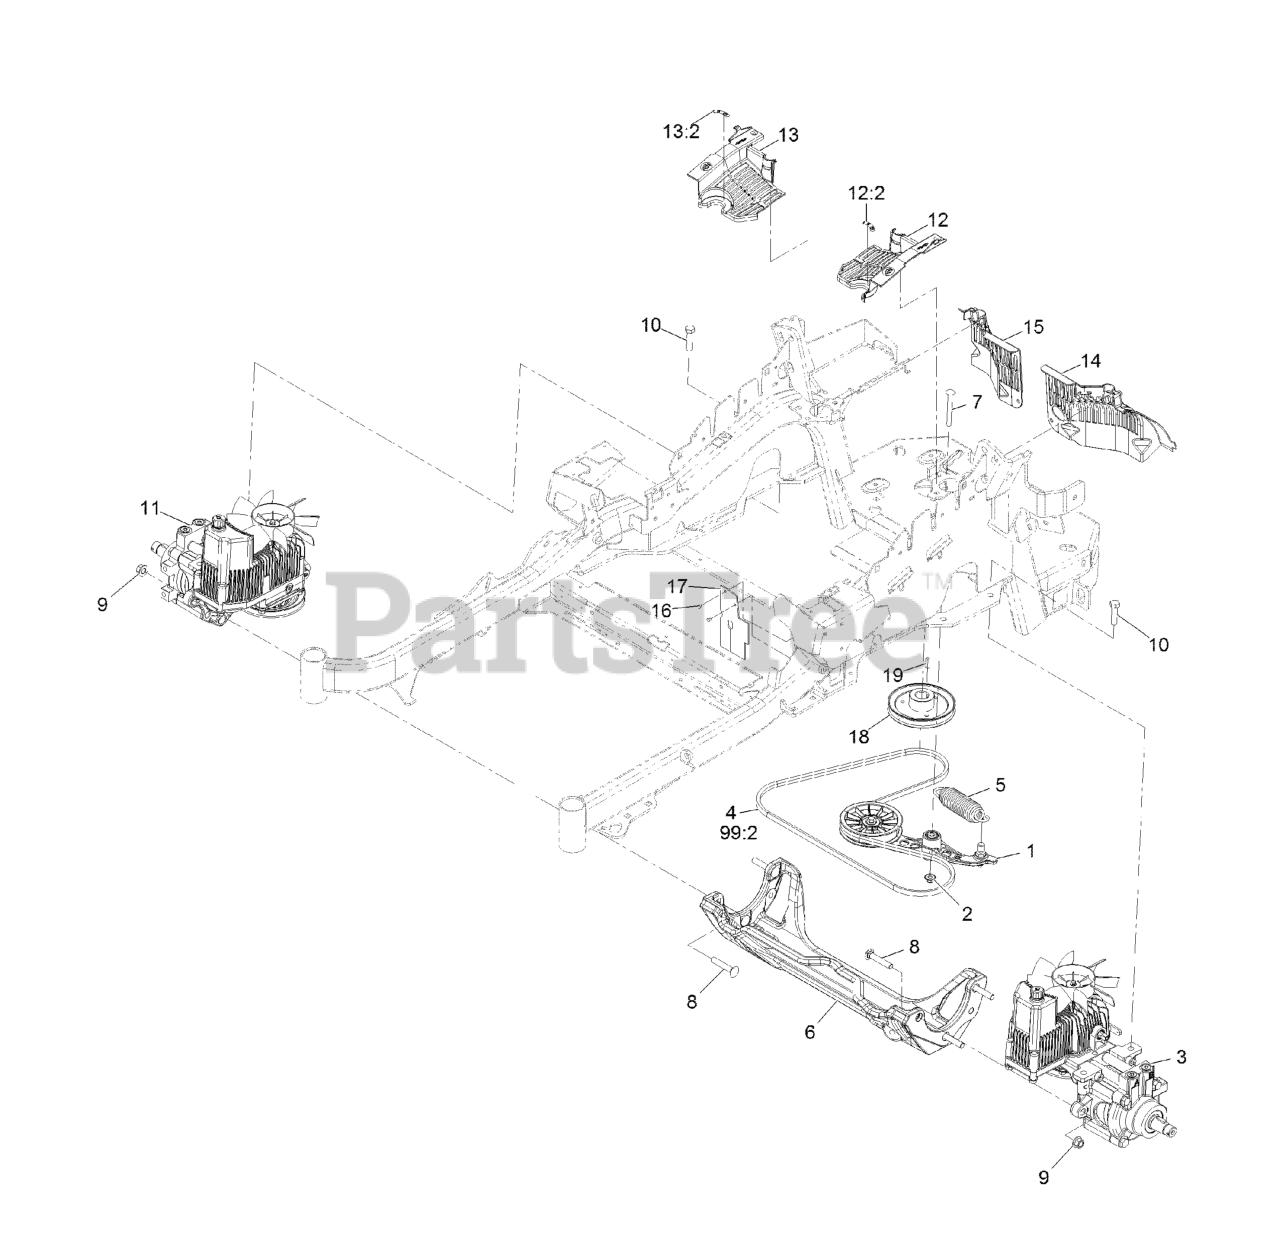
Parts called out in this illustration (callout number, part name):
1	PUMP IDLER ASM
2	Nut-Nyloc 3/8-16 Flg
3	LH HYDRO ASM (12CC W/ CHECK)
5	SPRING-EXTENSION
6	CRADLE-HYDRO
7	BOLT-SHOULDER, CARRIAGE 3/8-16 X 3 1/2
8	SCREW-CARR
9	Nut-Lock 1/2-13
10	SCREW-HH
11	RH HYDRO ASM (12CC W/ CHECK)
12	LH HYDRO GUARD ASM
12:2	DECAL-OIL, HYDRO
13	RH HYDRO GUARD ASM
13:2	DECAL-OIL, HYDRO
14	GUARD-HYDRO, REAR (LH)
15	GUARD-HYDRO, REAR (RH)
16	RIVET-POP
17	DEFLECTOR-AIR FLOW
18	SHEAVE
99:2	BELT
